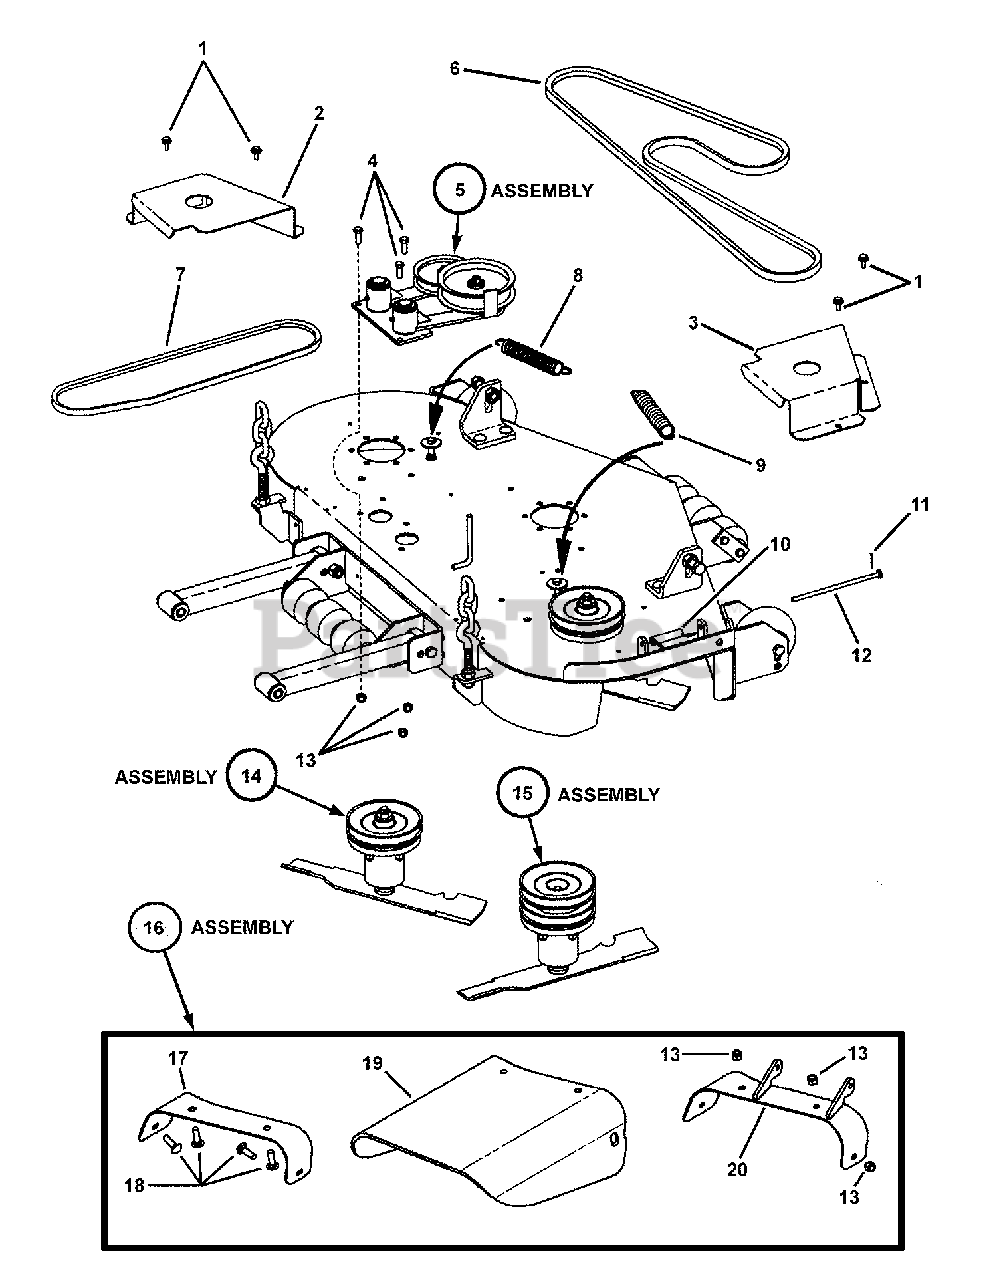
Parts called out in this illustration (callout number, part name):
1	SCREW, 5/16-18 x 5/8" Hex Washer Self-Tap
2	BELT COVER, Left Hand
3	BELT COVER, Right Hand
4	BOLT, 3/8-16 X 1" GD5 CZ
5	ASSEMBLY, Idler (see breakdown on Idler Assy page)
6	*V-BELT, Secondary- 52" (HB Section, 116.30" effective length)
7	*BELT, Primary (HB Section, 91.30" effective length)
8	SPRING, Idler (1.17" O.D. x 7.5" long)
9	SPRING, Idler Primary (1.25" O.D. x 10" long)
10	SPRING, Chute
11	PIN, 3/32 x 1" Cotter
12	PIN, Chute Hinge
13	NUT, 3/8-16 HEX NYLON LOCK
14	ASSEMBLY, Spindle (see breakdown on Deck Spindle Assy page)
15	ASSEMBLY, Center Spindle (see breakdown on Deck Spindle Assy page)
16	ASSY, Discharge Chute, 52" Deck
17	DEFLECTOR BOTTOM (52" Deck)
18	BOLT, 3/8-16 x 1-1/4" Square Neck Carriage, GR 5
19	DEFLECTOR, 52" Chute (Rubber)
20	WELDMENT, 52" Discharge Chute
